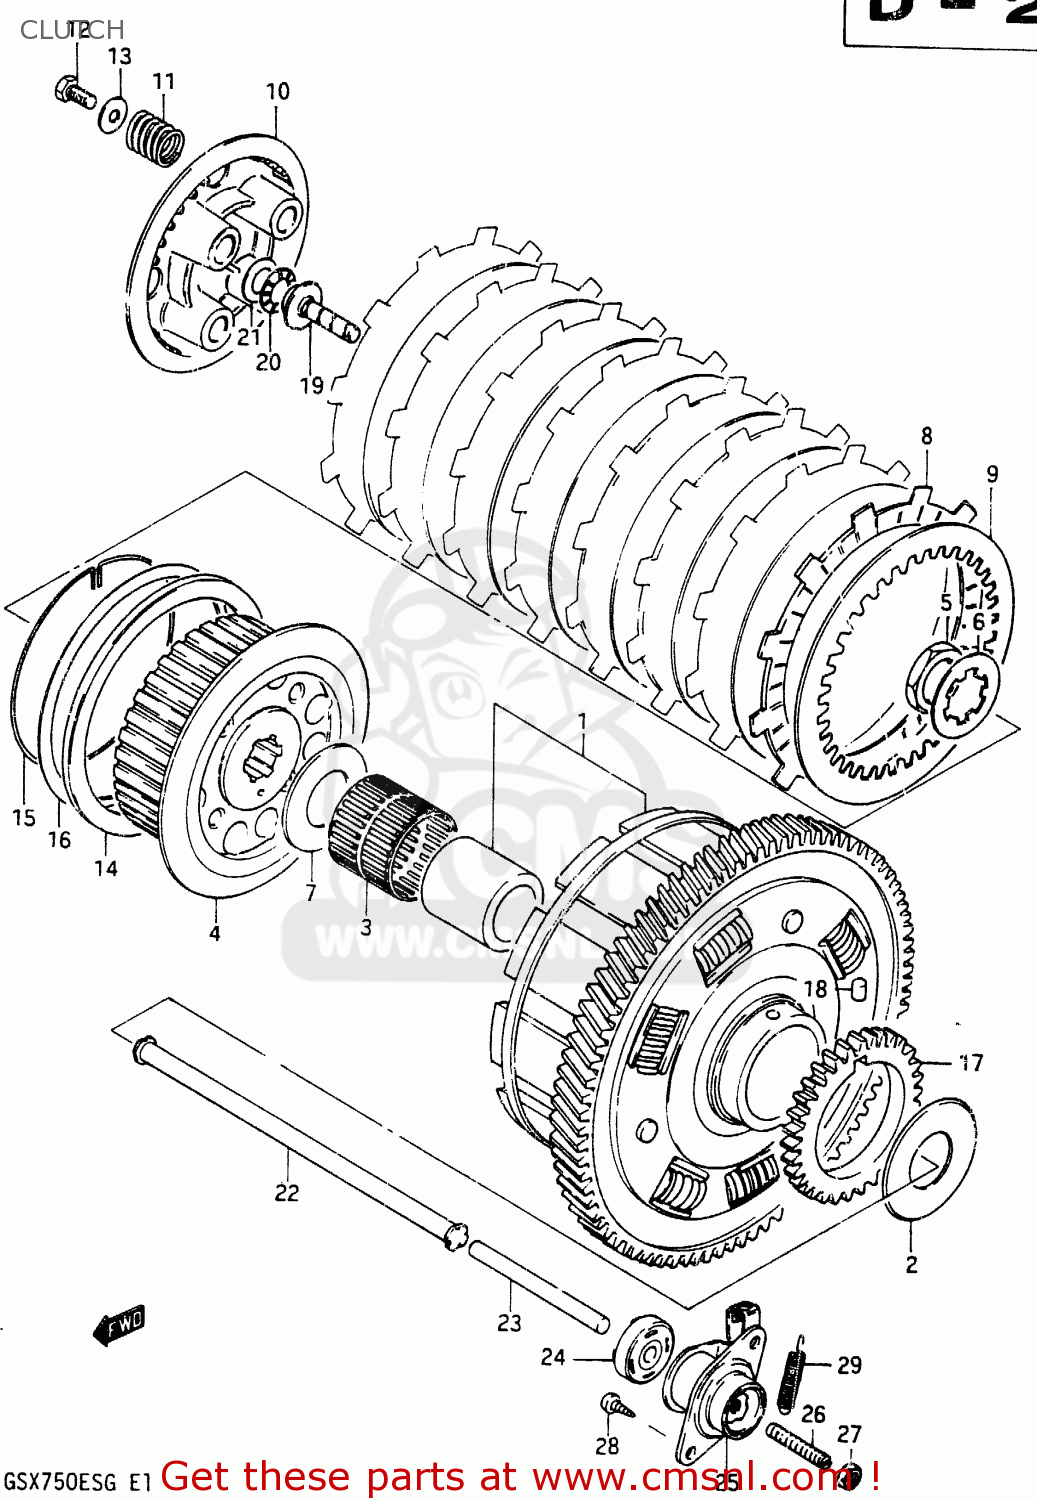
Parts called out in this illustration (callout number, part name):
1	GEAR ASSEMBLY,PRIMARY DRIVE
2	WASHER(25X54X2.5)
3	BEARING(35X40X39.8)
4	HUB,CLUTCH SLEEVE
5	NUT
6	WASHER,LOCK
7	WASHER(25X50X2.5)
8	PLATE,CLUTCH DRIVE (MCA)
9	PLATE,CLUTCH DRIVEN(T:2.0) (NAS)
10	PLATE,CLUTCH PRESSURE
11	SPRING
12	BOLT
13	WASHER
14	SEAT,WAVE WASHER
15	RING,STOPPER
16	WASHER
17	GEAR,OIL PUMP DRIVE
18	PIN(6X6)
19	PIECE,CLUTCH PUSH
20	BEARING(15X28X2)
21	WASHER
22	ROD,CLUTCH PUSH
23	ROD,CLUTCH PUSH,L
24	SEAL,OIL(6X34X7.5)
25	SCREW ASSY,CLUTCH RELEASE
26	SCREW(6X25)
27	NUT 6MM
28	SCREW
29	SPRING
